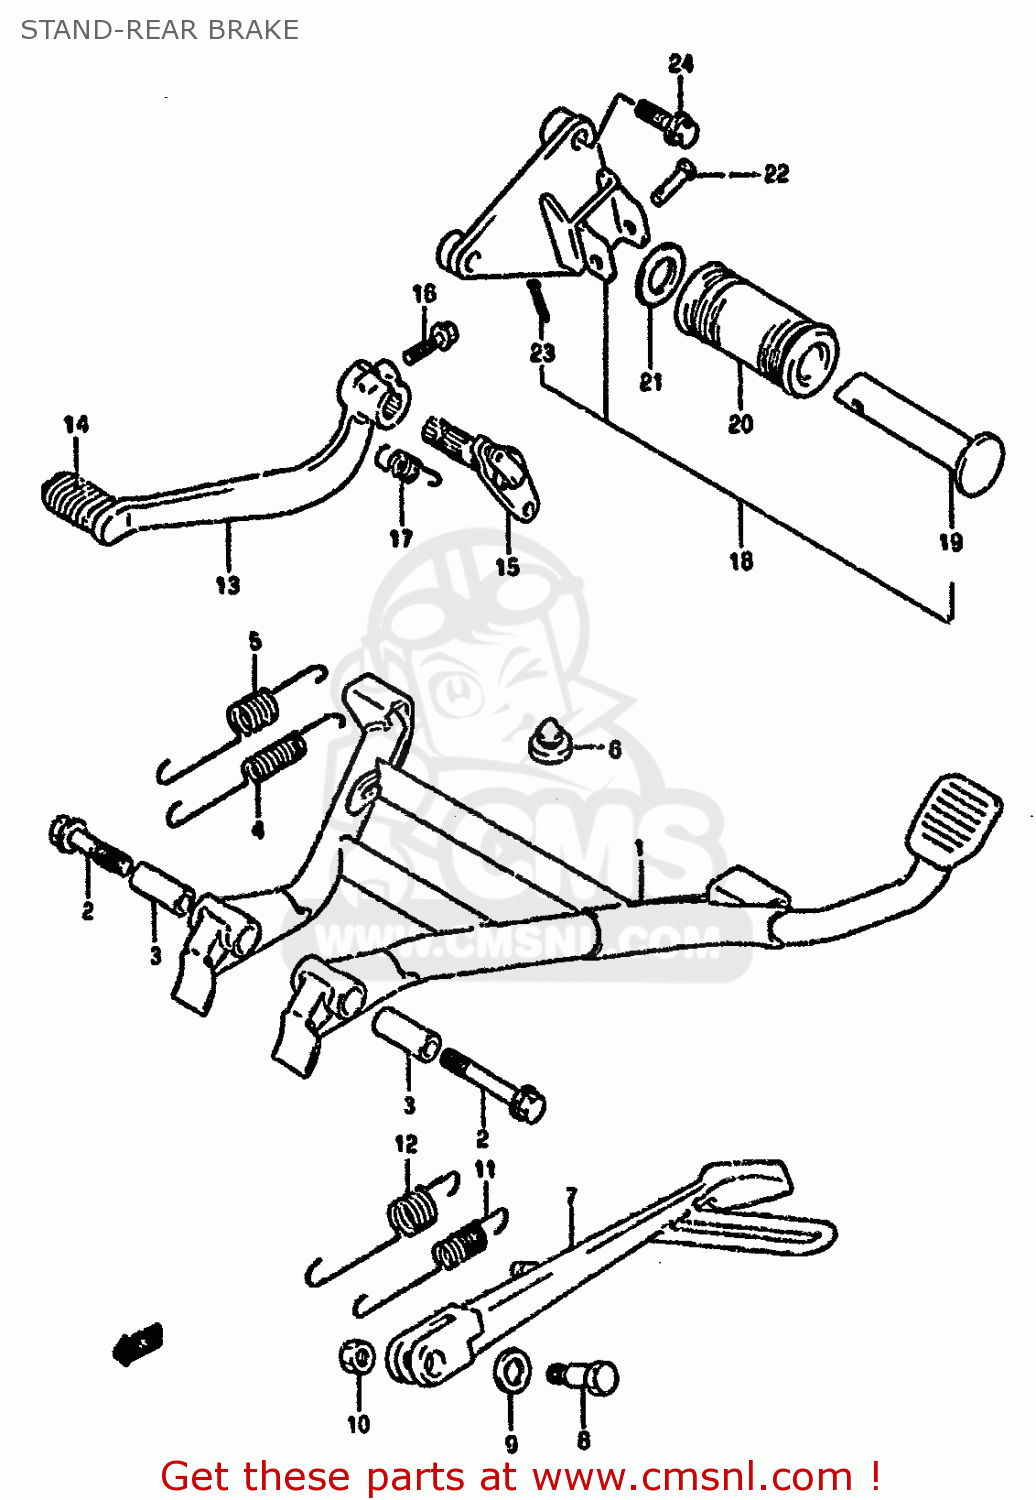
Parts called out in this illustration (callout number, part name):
1	STAND,PROP.
2	BOLT(10X60)
3	SPACER(10X16X38.8)
4	SPRING
5	SPRING OUTER
6	CUSHION
7	STAND,PROP
8	BOLT(10X38)
9	SHIM
10	NUT
11	SPRING
12	SPRING
13	PEDAL COMP,BRAKE
14	RUBBER,PEDAL
15	ARM,BRAKE ROD
16	BOLT
17	SPRING,BRAKE PEDAL
18	GRIP SET,CENTER STAND
19	BAR,PILLION FOOTREST
20	RUBBER,STAND GRIOP (OPT)
21	WASHER (19.5X32X2)
22	PIN
23	PIN
24	BOLT
